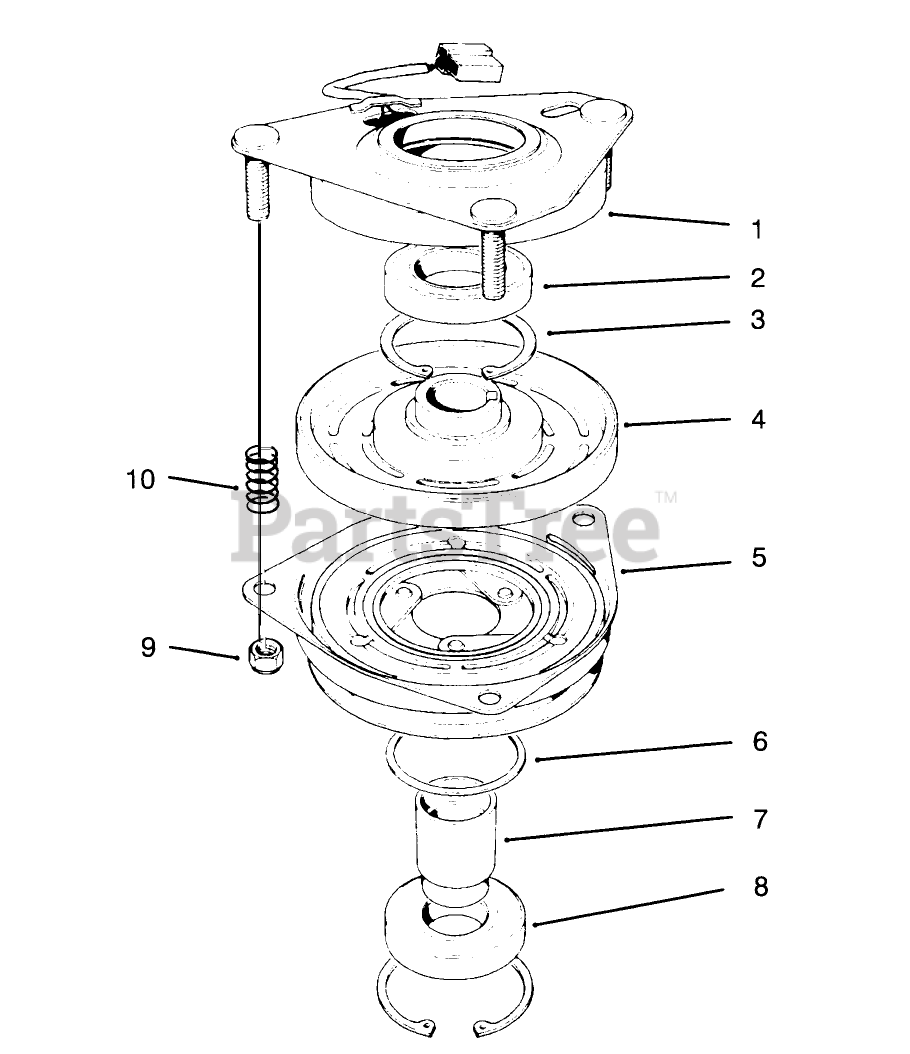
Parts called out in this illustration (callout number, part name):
1	FIELD BEARING ASM
2	BEARING-FIELD
3	RING-RETAINING
4	FIELD COIL/ROTOR BEARING ASM
6	SPACER-BEARING, PULLEY
7	COLLAR-BEARING
9	NUT-HEX
10	SPRING
